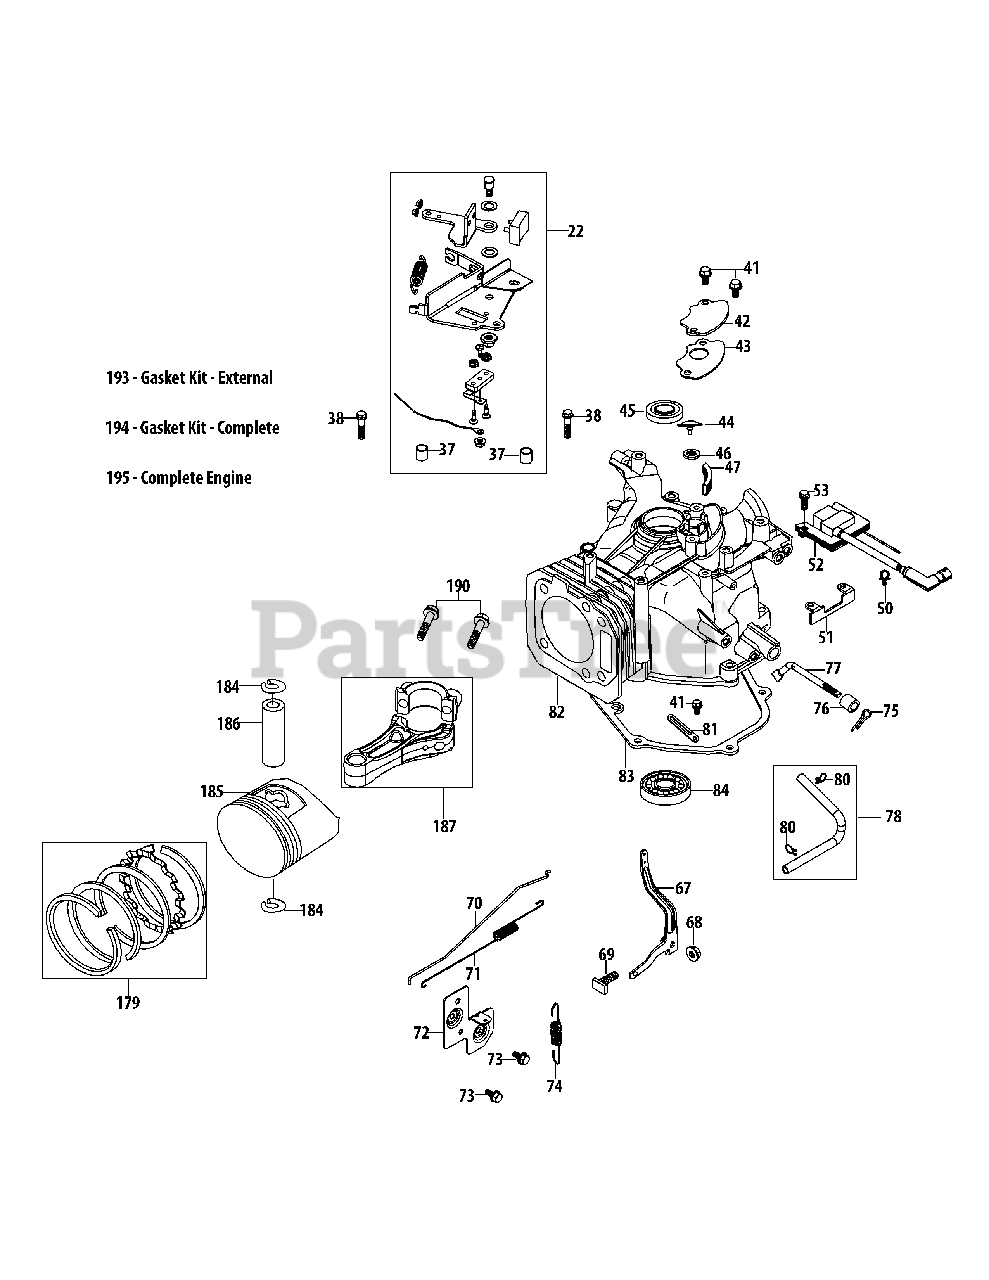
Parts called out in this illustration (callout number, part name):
22	Stop Switch & Brake Assy
37	Brake Spacer
38	Bolt M6X35
41	Bolt M6X14 Multi-Purpose
42	Breather Cover Plate
43	Breather Gasket
44	Breather Valve
45	Upper Crankshaft Seal
46	Breather Valve Base
47	Breather Screen
50	Ignition Wire Clip
51	Ignition Coil Bracket
52	Ignition Coil Assembly
53	Bolt M6X18
67	Governor Arm
68	Governor Arm Nut M6
69	Governor Arm Bolt
70	Throttle Linkage
71	Throttle Linkage Spring
72	Component Bracket
73	Bolt M6X12
74	Governor Spring
75	Governor Arm Shaft Cotter Pin
76	Governor Seal
77	Governor Arm Shaft
78	Breather Hose Assembly
80	Breather Hose Clamp
81	Flexible Clamp
82	Short Block Assembly
83	Crankcase Cover Gasket
84	Main Bearing
179	Piston Ring Set
184	Piston Pin Snap Ring
186	Piston Pin
187	Connecting Rod Assembly
190	Connecting Rod Bolt
193	Gasket Kit - External
194	Gasket Kit - Complete
195	Complete Engine
